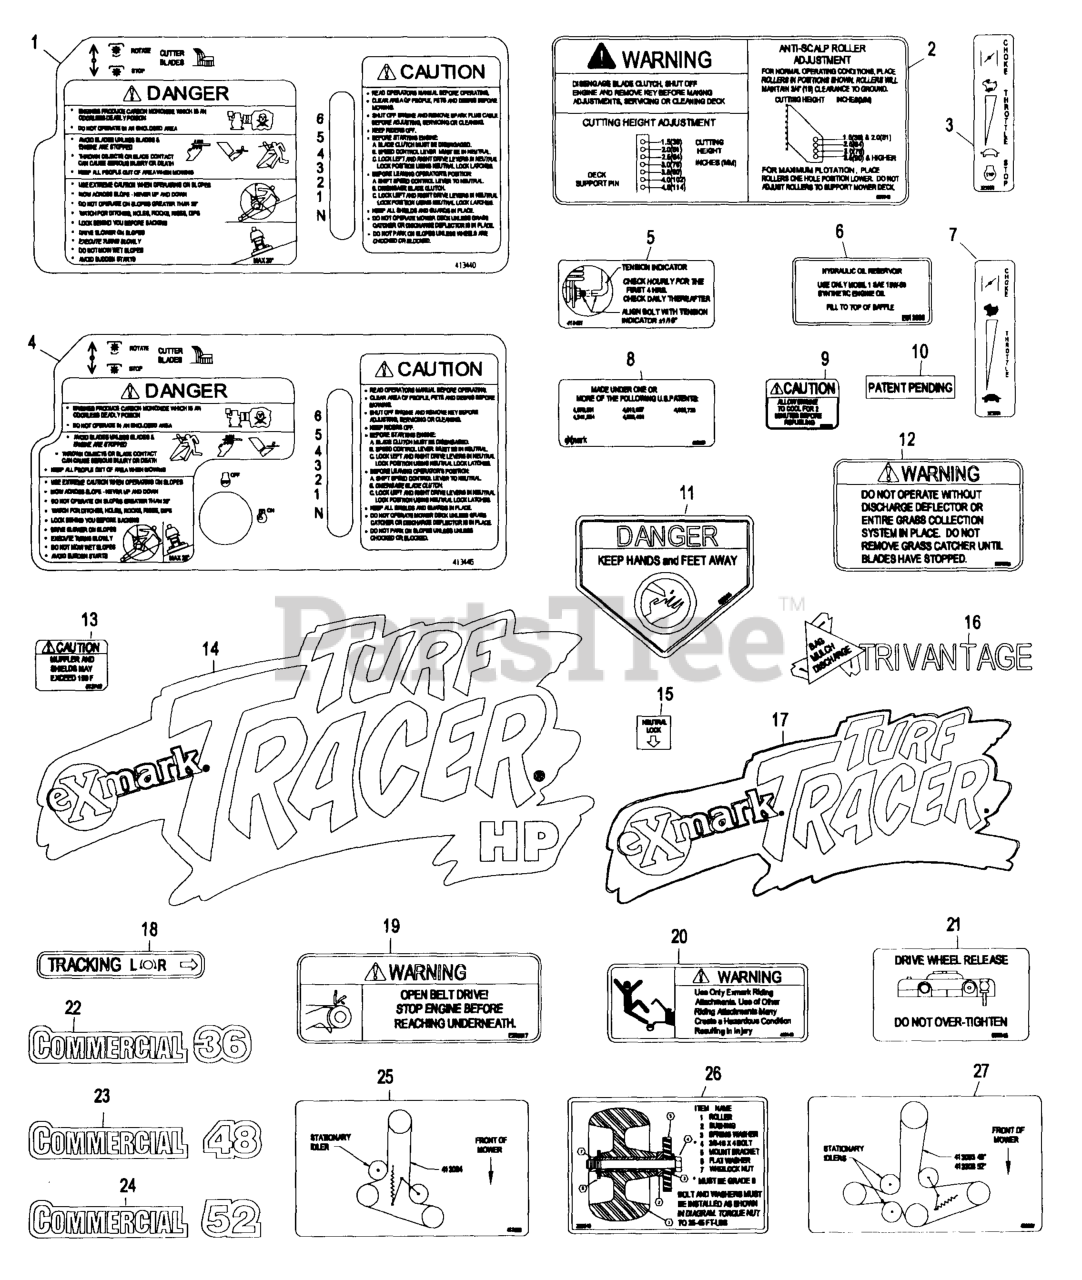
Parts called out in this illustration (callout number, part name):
2	Decal, Mowerdeck
5	DECAL,INDICATOR
6	DECAL,HYD TANK
7	DECAL,THROTTLE
10	Decal, Patent Pending
11	DECAL-DANGER
12	DECAL-WARNING, DISCHARGE
15	DECAL,NEUTRAL LOCK
18	DECAL,TRACKING ADJUST
19	DECAL,BELT DRIVE
20	DECAL,SULKY WARNING
21	DECAL,DRIVE RELEASE
22	DECAL,COMMERCIAL 36
23	DECAL,COMMERCIAL 48
24	DECAL,COMMERCIAL 52
25	DECAL,BELT ROUTING
26	DECAL,ROLLER MOUNTING
27	DECAL,BELT ROUTING
